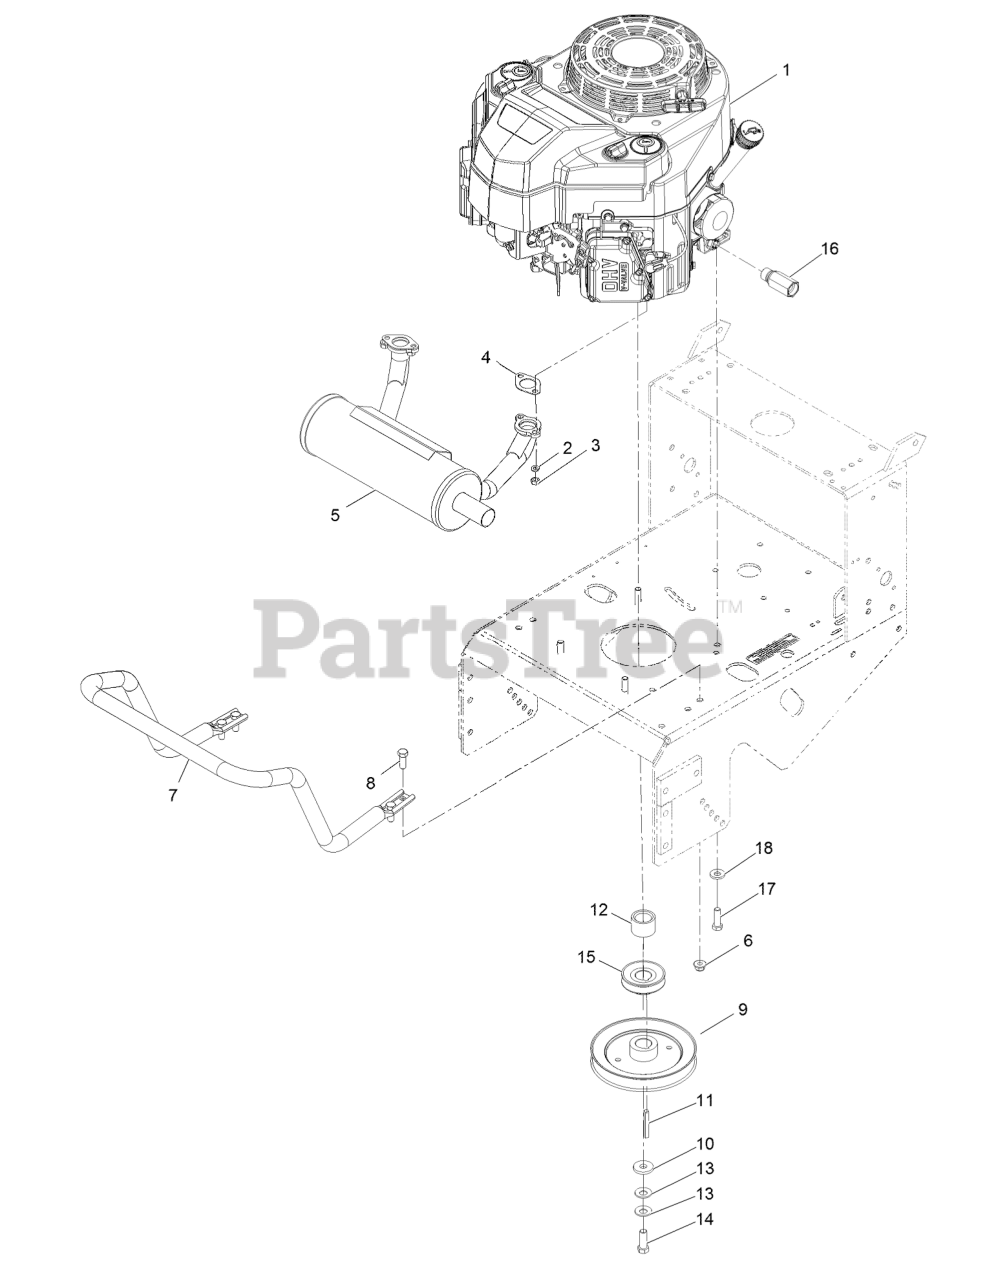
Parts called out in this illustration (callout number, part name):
1	Engine-Kawasaki
2	WASHER-LOCK
4	GASKET-EXHAUST
5	MUFFLER-HORIZONTAL, OFFSE
6	NUT-HF, NI
7	GUARD-MUFFLER
8	SCREW-HH
12	SPACER-CLUTCH
13	WASHER-SPRING
14	SCREW-HH
15	SHEAVE-TRANSMISSION
16	ADAPTER
17	SCREW-HH
18	WASHER-BELLEVILLE
